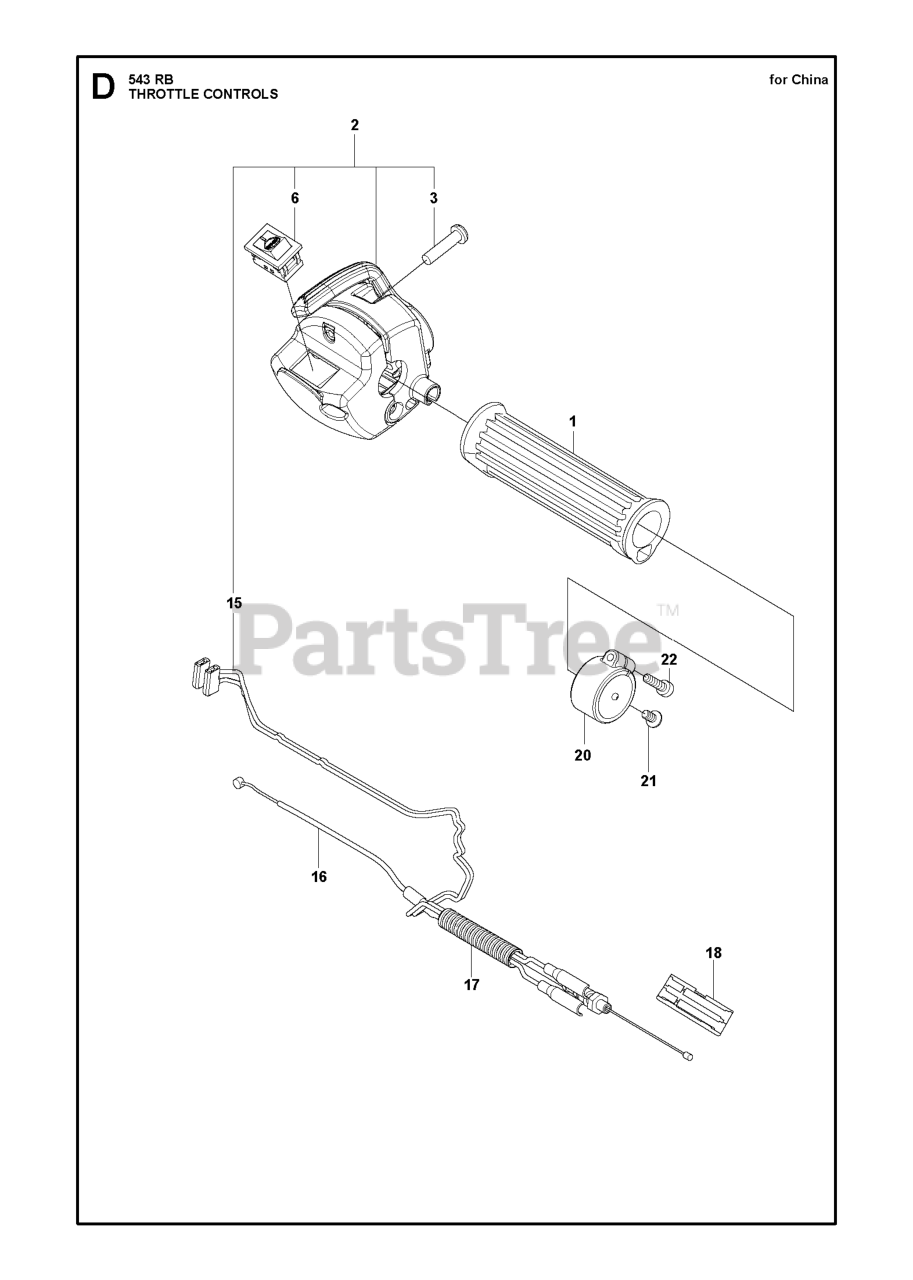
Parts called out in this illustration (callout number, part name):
6	STOP SWITCH NM_09091801
20	CLAMP
22	BOLT
